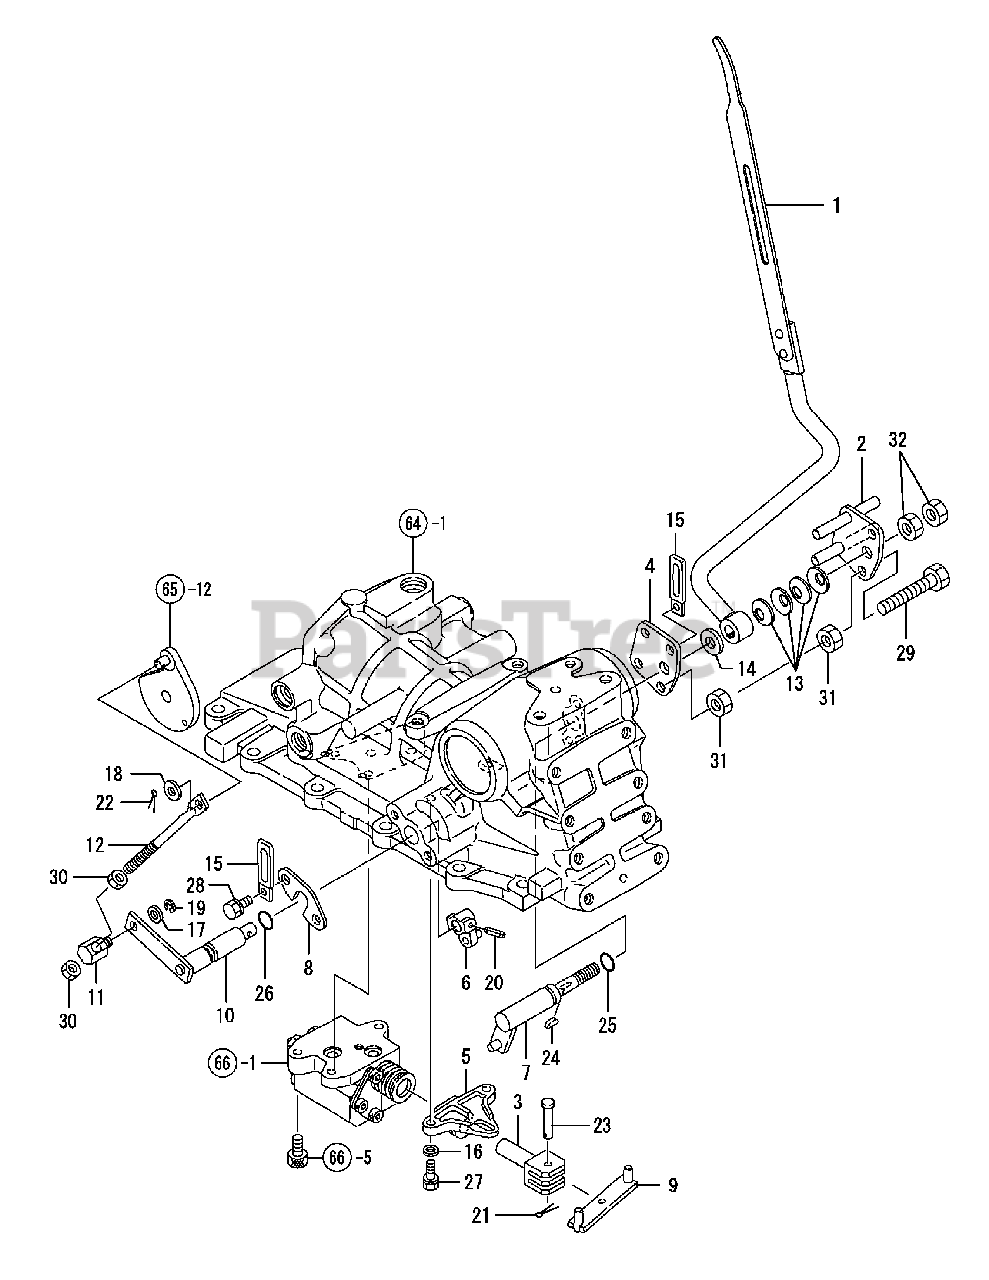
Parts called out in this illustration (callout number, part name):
1	LEVER,PRESS.CONTROL
2	PLATE,FRICTION
5	PLATE, CONTROL
6	ARM,P CONTROL F.BACK
7	SHAFT, CONTROL LEVER
12	ROD, FEED BACK
14	PLATE, FRICTION
15	CLAMP, WIRE HARNESS
16	WASHER 8, POLISHED
17	WASHER 10,POLISHED
18	WASHER 10,POLISHED
20	SPRING PIN 5X25
21	COTTER PIN 2.0X16
22	COTTER PIN 3.0X20
24	WOODRUFF KEY 3X13
25	O-RING 1A P-15.0
26	O-RING 1A P-15.0
27	BOLT W/WASHER M8X20
29	BOLT M10X 50 PLATED
